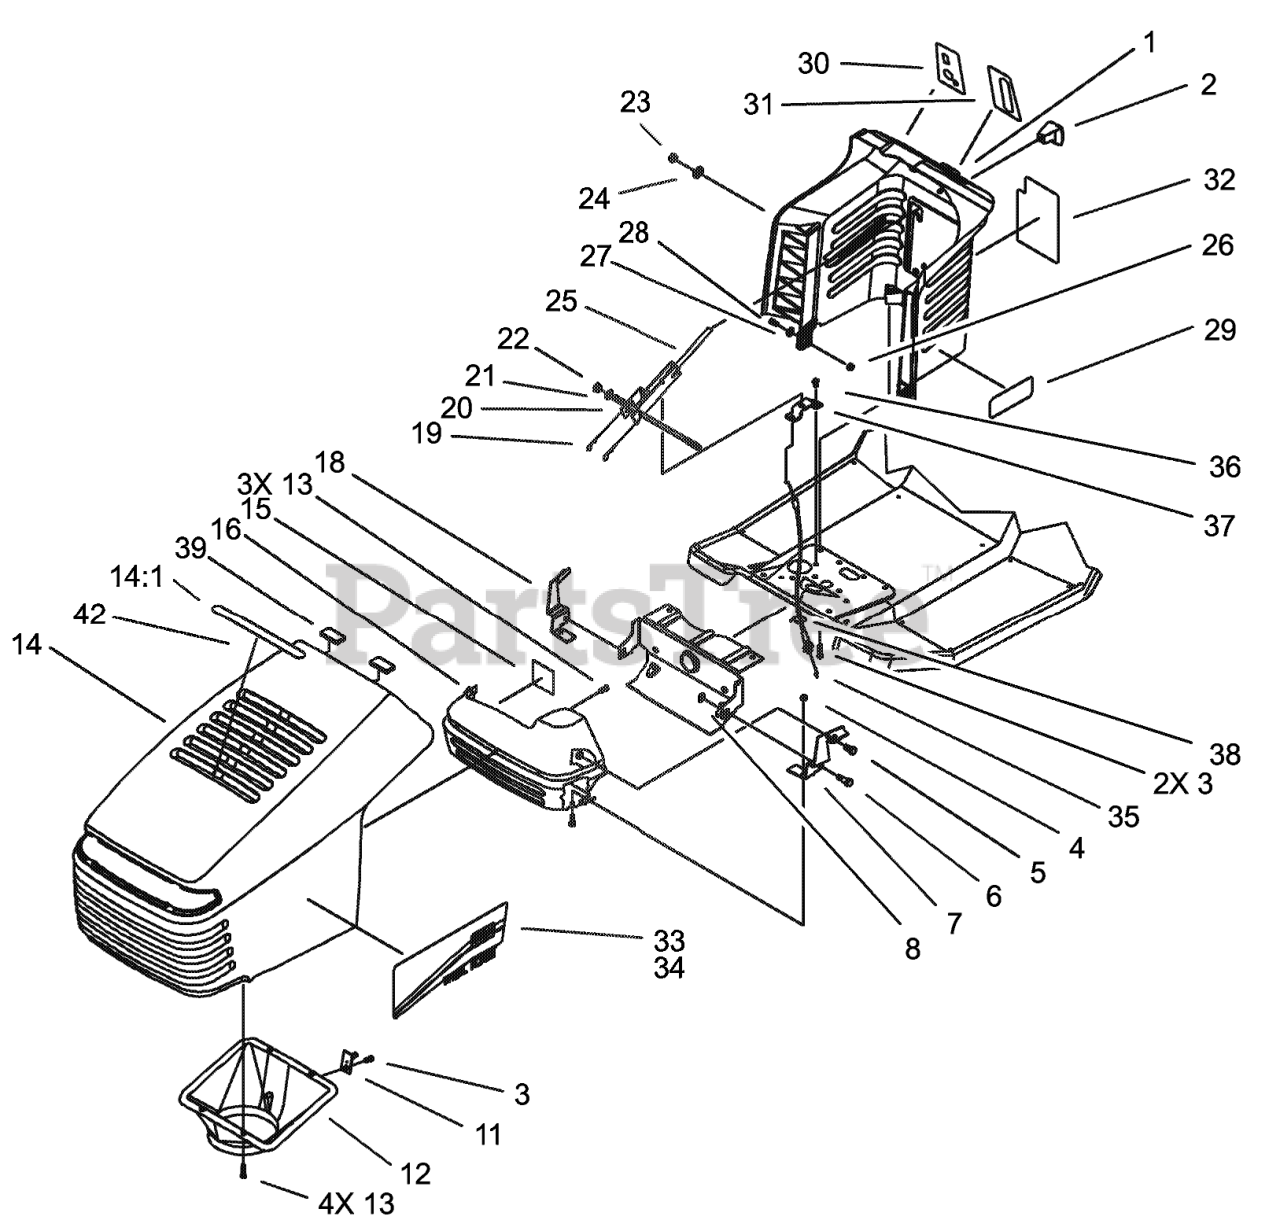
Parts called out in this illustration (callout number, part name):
1	TOWER-STEERING
2	KNOB-SHIFT
3	SCREW-HWH
4	NUT-LOCK, NI
5	SCREW-HH
6	BOLT-SHOULDER
7	BRACKET-PIVOT, LH HOOD
8	NUT-RETAINER
11	LATCH-PIN
12	DUCT-AIR, HOOD
13	SCREW-PLASTITE
14	HOOD ASM
14:1	DECAL-AIR DUCT
15	TAPE-FOIL
16	SHIELD-HEAT
18	BRACKET-PIVOT, RH HOOD
19	PIN-COTTER
20	ROD-TOWER, PIVOT
21	WASHER-FLAT
22	NUT-JAM
23	NUT-CAP
24	WASHER-FLAT
25	LEVER-DECK, ENGAGE
26	NUT-LOCK, NI
27	WASHER-PLAIN
28	SCREW-HH
29	DECAL-TOWER 1744 HXL
30	DECAL-IGNITION/LIGHTS
31	DECAL-THROTTLE/CHOKE
32	DECAL-DECK, ENGAGE
33	DECAL-HOOD, LEFT
34	DECAL-HOOD, RIGHT
35	DECK CABLE ASM
36	SCREW-HWH
37	BRACKET-CABLE, UPPER
38	TIE-CABLE
39	FOAM-HOOD
